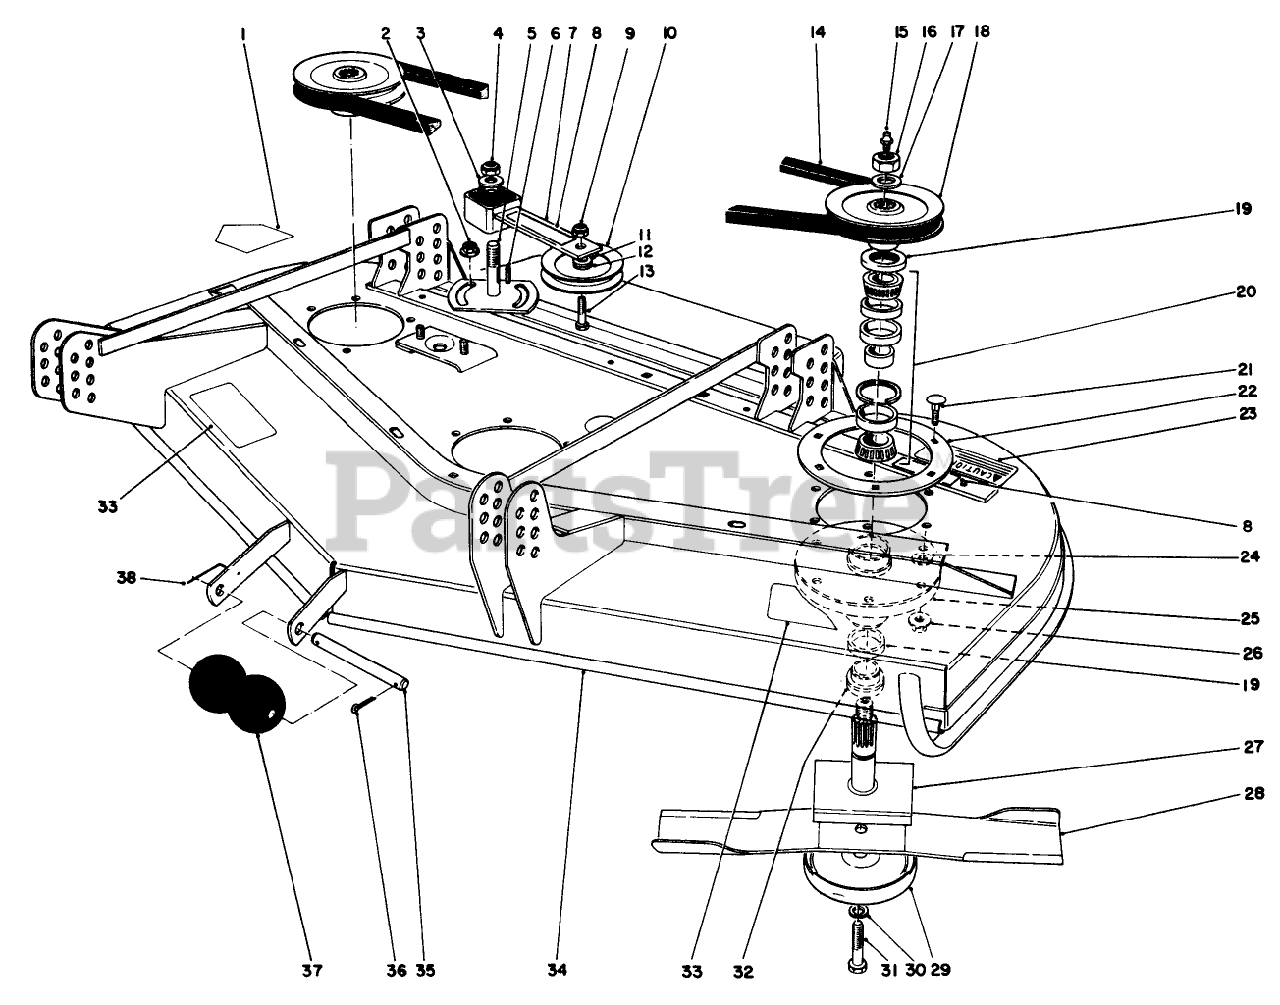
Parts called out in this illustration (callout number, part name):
1	DECAL-DANGER
2	Nut-HFH
3	WASHER-FLAT
4	NUT-LOCK, NI
5	PLATE-IDLER
6	KEY-SQUARE
7	IDLER ARM ASM
8	DECAL-DANGER
9	NUT-HEX
10	PULLEY-IDLER
11	WASHER-FLAT
12	BUSHING-PULLEY
13	SCREW-HH
14	V-BELT
15	FITTING-GREASE
16	NUT-HEX
17	WASHER
18	PULLEY AND HUB ASM
19	SEAL-OIL
20	BEARING ASM
21	SCREW-CARR
22	SUPPORT-DECK, RING
23	DECAL-TORQUE
24	WASHER-FLAT
25	HOUSING-SPINDLE
26	NUT-HF
27	SHAFT
28	Blade
29	CUP-SCALP, ANTI
30	WASHER-LOCK
31	SCREW-BLADE
32	SPACER
33	DECAL-DANGER, THROWN OBJECT
34	Cutting Deck
35	SHAFT-ROLLER
36	PIN-COTTER
37	ROLLER
38	PIN-SPECIAL
